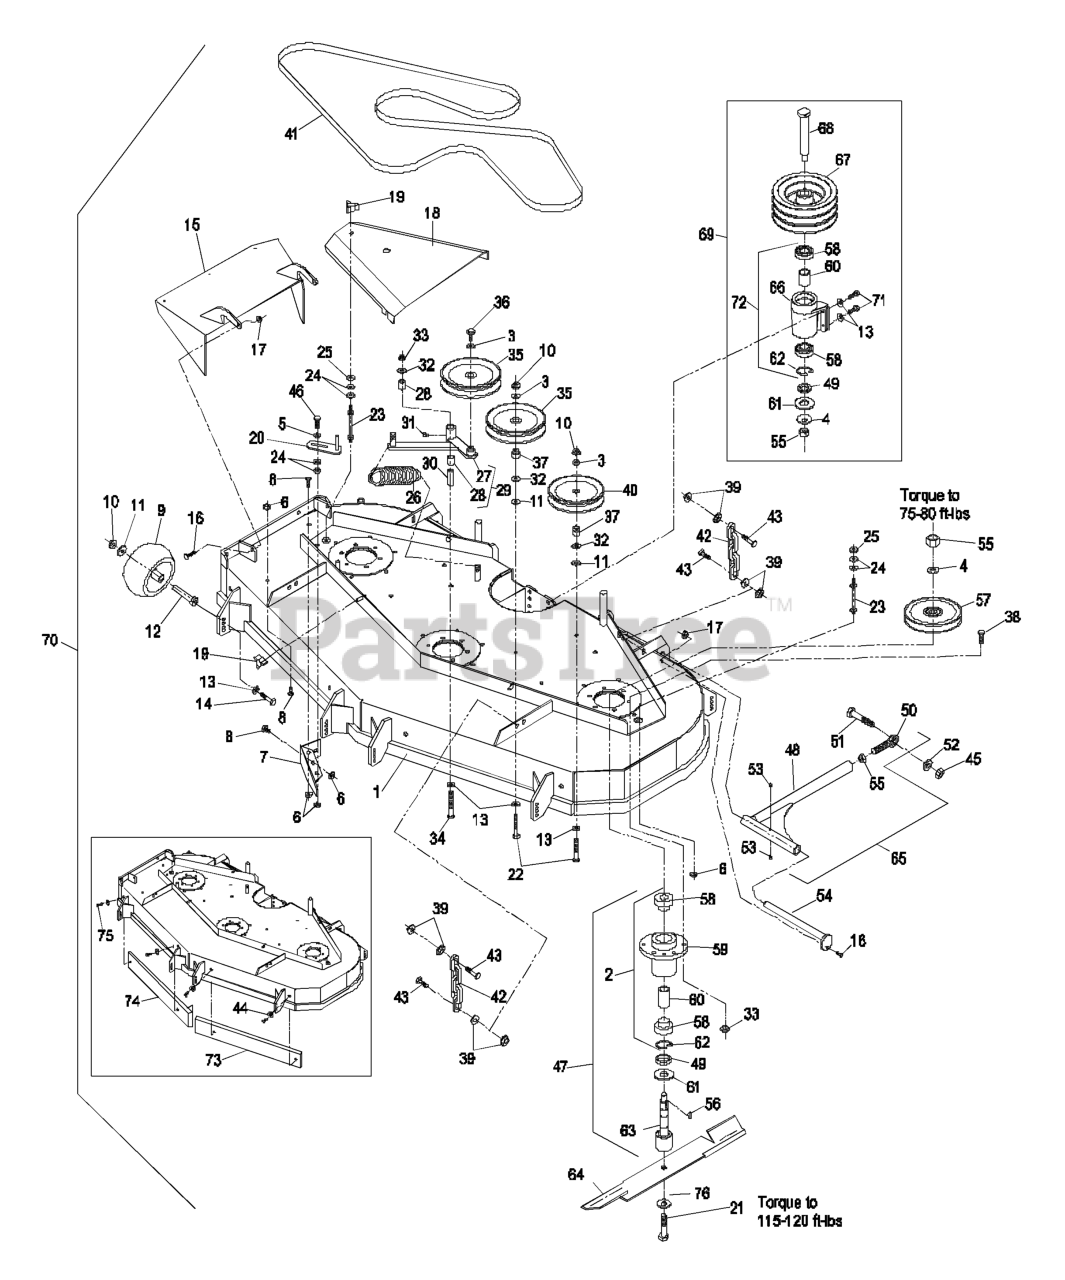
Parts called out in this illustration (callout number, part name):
3	WASHER-FLAT
4	WASHER-SPRING
5	WASHER-SPRING
7	WLD,BAFFLE DISCHARGE
8	SCREW-HH
9	ROLLER-SCALP, ANTI
10	NUT-HHF, WHIZ
12	BUSHING-ROLLER
13	WASHER-BELLEVILLE
14	SCREW-HH
16	SCREW-HH
17	NUT-LOCK, NI
18	SHIELD,BELT
19	KNOB-3 PRONG
20	GUIDE-BELT
21	SCREW-CAP
22	SCREW-HH
23	STUD-SHIELD, BELT (SHORT)
24	WASHER-FLAT
28	SLEEVE-BEARING
30	BUSHING
31	FITTING-GREASE, 90 DEG
32	WASHER-FLAT
33	NUT-LOCK, NI
34	SCREW-HH
36	SCREW-HHF
37	BUSHING-IDLER
38	SCREW-HH
40	PULLEY-IDLER
41	BELT,BLADE DRIVE
42	CHAIN-LIFT, DECK
43	SCREW-CAP, HH
44	WASHER-SPRING
45	NUT-HEX
46	SCREW-HH
47	ASM,SPINDLE HSG COMPLETE
49	SPACER-PULLEY/BEARING
50	BALLJOINT-SPHERICAL
51	SCREW-HH
52	WASHER-LOCK
53	FITTING-GREASE
54	PIN-STRUT
55	NUT-HEX
56	KEY-WOODRUFF
57	SHEAVE,BLADE DRIVE
58	BEARING
60	SPACER-BEARING
61	GUARD-BEARING, BOTTOM
62	RING-SNAP
65	STRUT ASM
68	JACKSHAFT,LAZER XP
69	ASM,JACKSHAFT
70	Complete Deck Assy
71	SCREW-HH
74	WEIGHT BAR ASM
75	SCREW-HH
76	WASHER-BLADE BOLT, HEAVY
